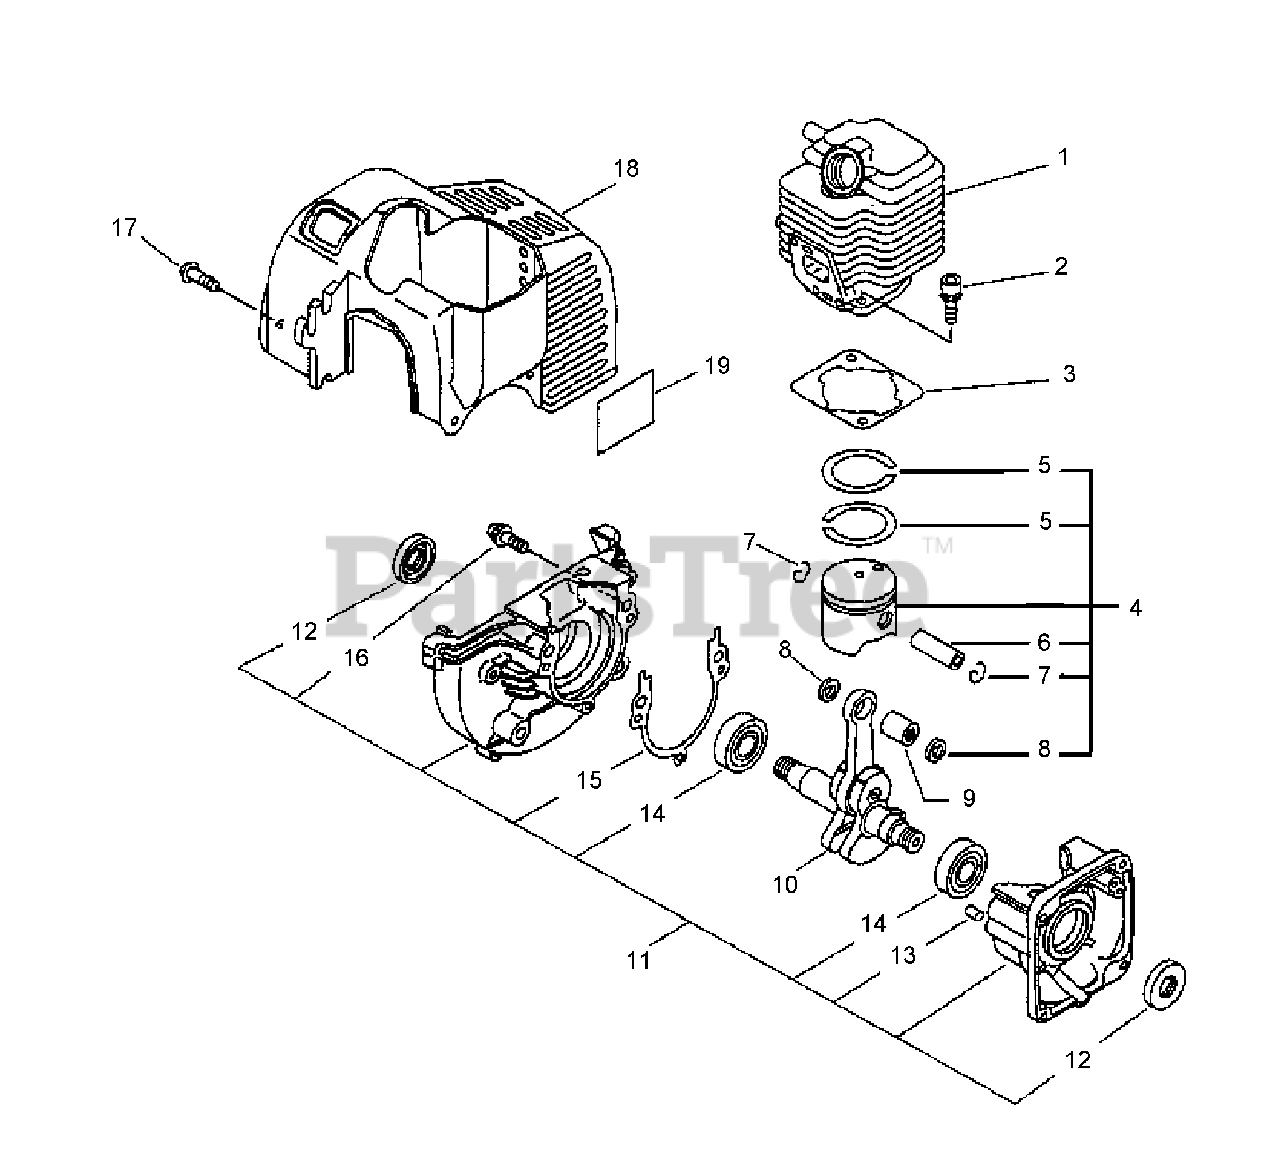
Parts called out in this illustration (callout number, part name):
1	CYLINDER
2	BOLT 5×22
3	GASKET, CYLINDER
4	PISTON KIT
5	RING, PISTON
6	PIN, PISTON 8
7	RING, SNAP
8	WASHER, THRUST
9	BEARING, NEEDLE
10	CRANKSHAFT ASSY
11	CRANKCASE KIT
12	SEAL, OIL 12
13	PIN, LOCATING 4
14	BEARING, BALL - 6201 C3
15	GASKET, CRANKCASE
16	BOLT 5×28
17	SCREW 4×12
18	COVER, ENGINE - GRAY
19	LABEL, MODEL
